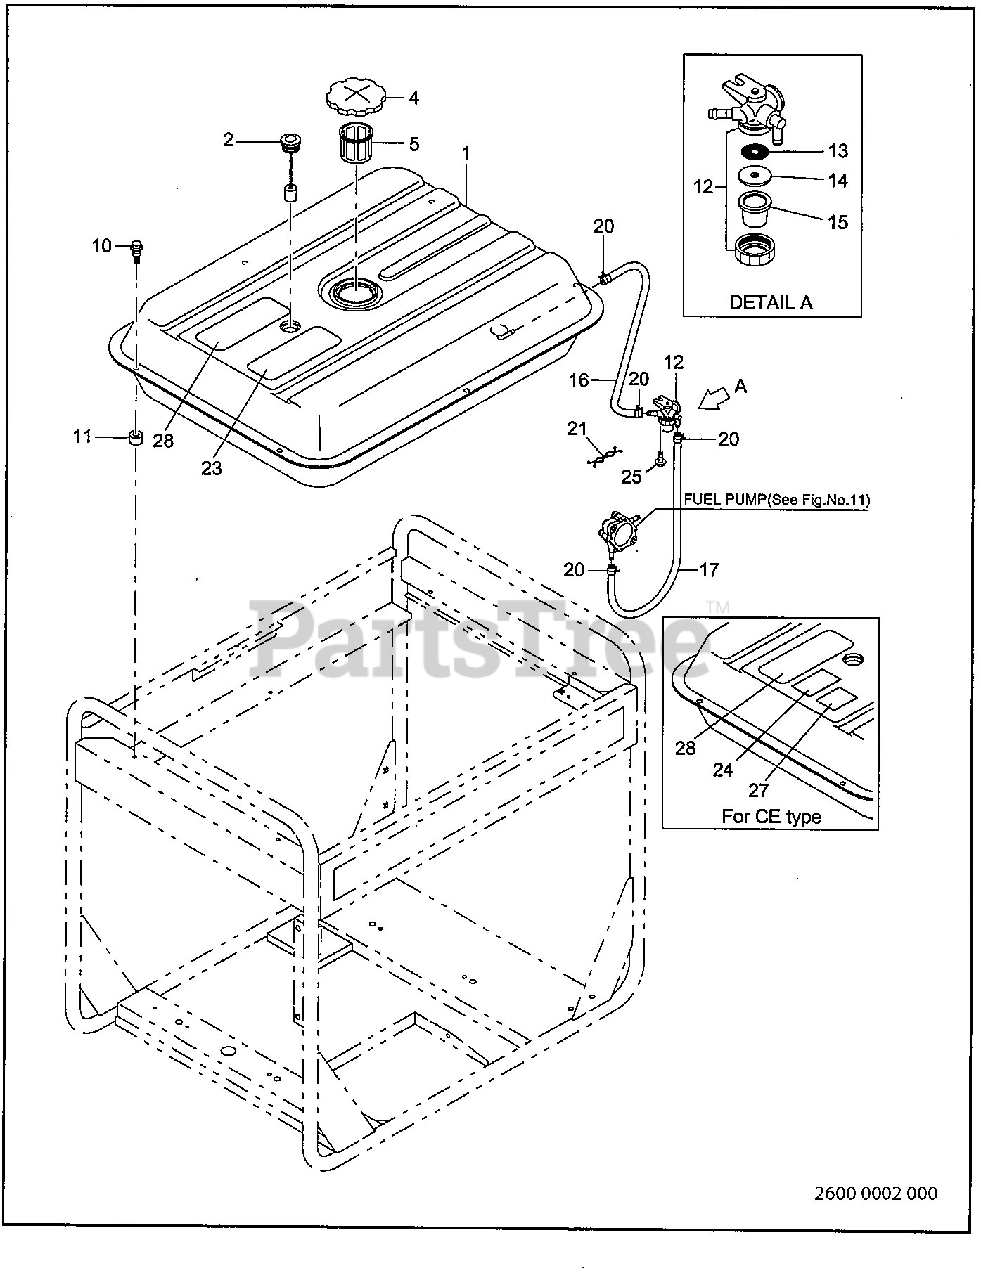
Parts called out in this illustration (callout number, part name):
1	FUEL TANK ASSY
2	FUEL GAUGE ASSY
4	FUEL TANK CAP ASSY
10	FLANGE BOLT
12	FUEL STRAINER ASSY
16	RUBBER PIPE
17	RUBBER PIPE
23	LABEL (caution)
24	LABEL (symbol-tank)
25	FLANGE BOLT
27	LABEL (LWA99)
28	LABEL (warning)
